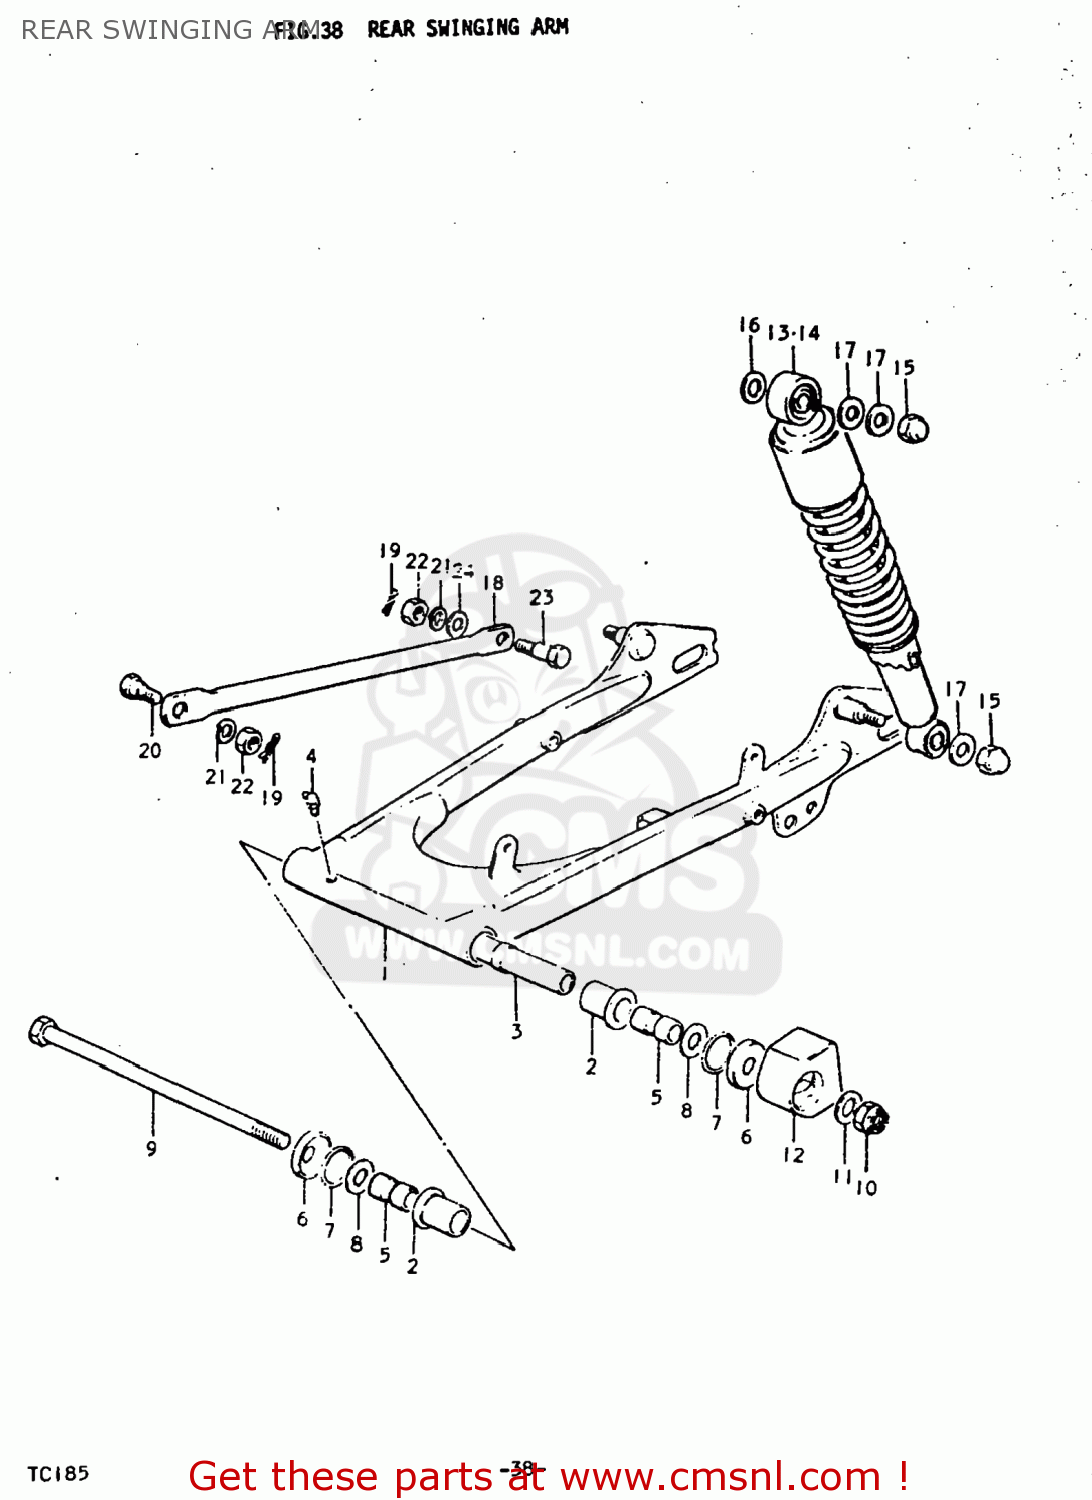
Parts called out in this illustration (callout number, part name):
1	SWING ARM ASSEMBLY,REAR
2	BUSH
3	SPACER,SWING ARM,CENTER
4	NIPPLE,GREASE
5	SPACER,RR SWGARM PIVOT
6	COVER,SWGARM BUSH DUST SEAL
7	O RING(D:2,ID:24.5)
8	WASHER(12.5X24X2.3)
9	SHAFT,PIVOT
10	NUT
11	WASHER
12	BUFFER,CHAIN TOUCH DEFENSE
13	ABSORBER ASSEMBLY,REAR SHOCK
14	ABSORBER ASSEMBLY,REAR SHOCK
15	NUT
16	WASHER
17	WASHER
18	TORQUE LINK,REAR
19	CLIP
20	BOLT(8X26.5)
21	LOCK WASHER
22	NUT
23	BOLT(8X22)
24	WASHER
